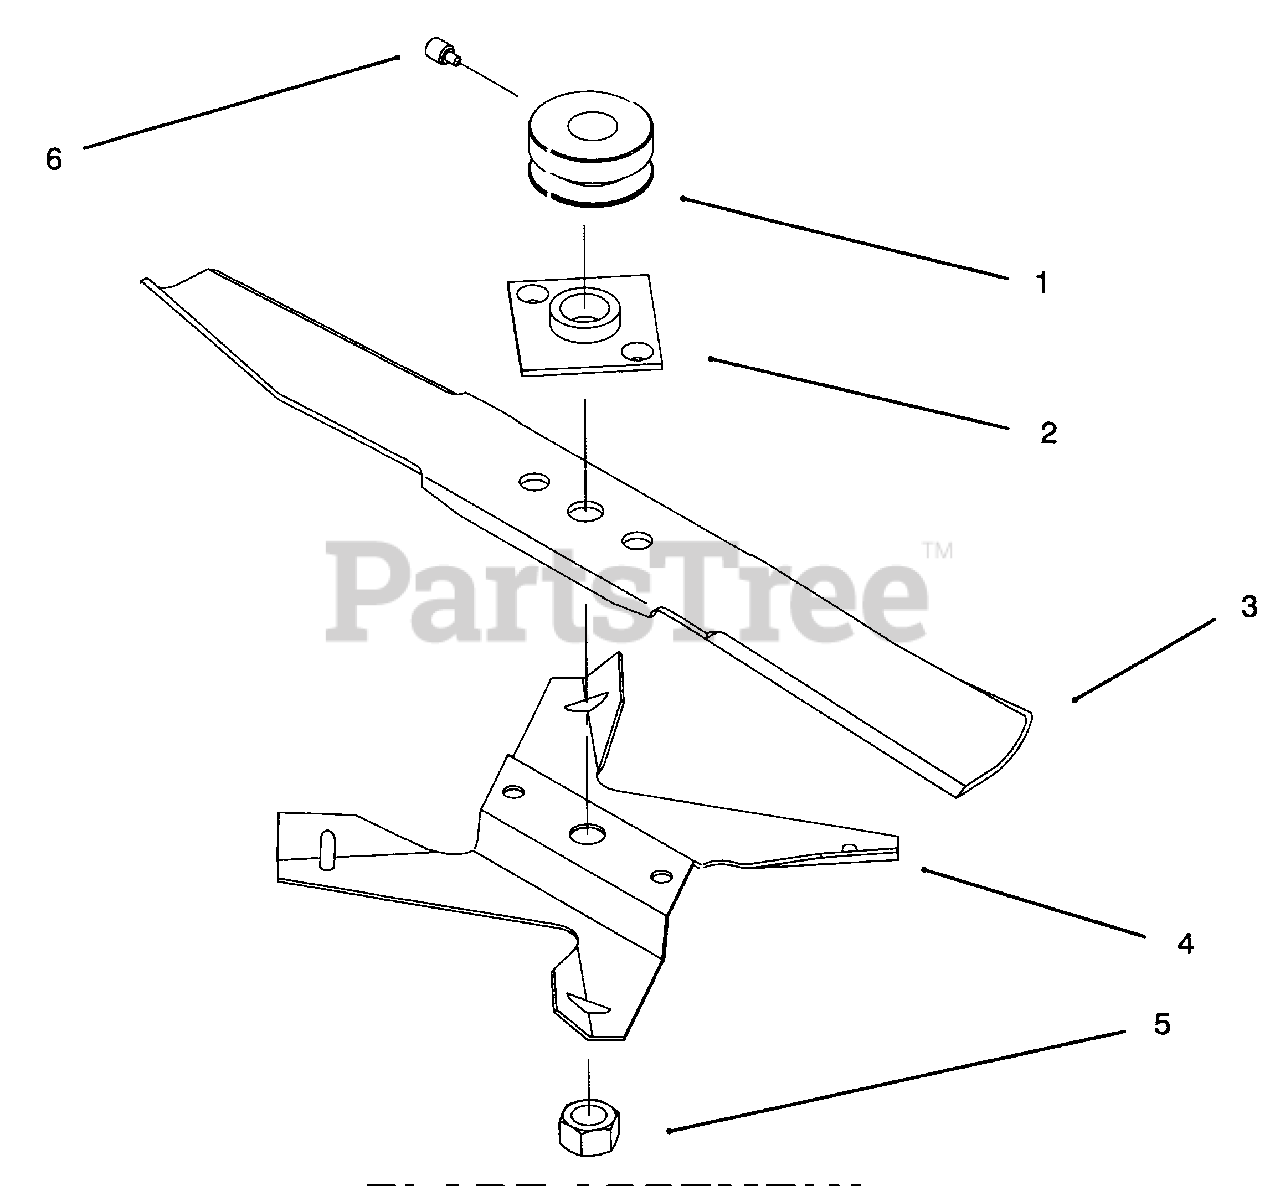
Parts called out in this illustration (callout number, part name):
1	Pulley-Engine (Model No. 10312 Only)
2	Plate & Collar
3	Blade-21"
4	Fan-Mulching
5	Nut-Blade
6	Screw-Set (Model No. 10312 Only)
